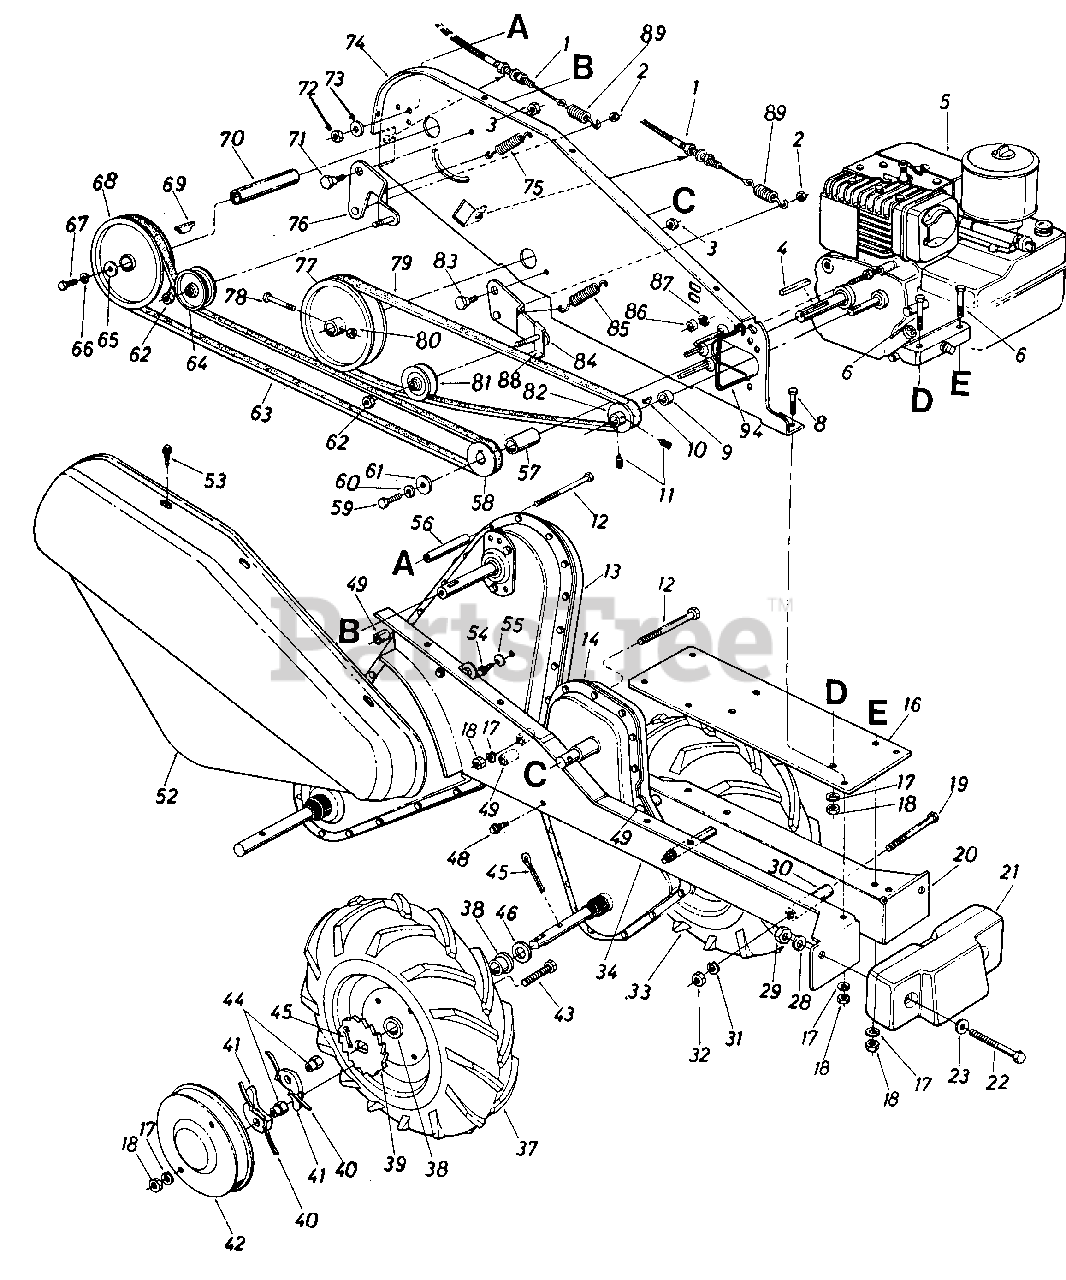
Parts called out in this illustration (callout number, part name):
1	CONTROL-CLUTCH
2	NUT-HEX CENTER L-1/4-20
3	NUT-HEX CENTER L-JAM
4	KEY-SQ 3/16 X .75
6	SCREW-HEX 5/16-18 X 1.50
8	SCREW-HEX 5/16-18 X .75
10	KEY-HI-PRO #5-1/8X5/8 DIA
11	SCREW-SET 1/4-28 X .25
12	SCREW-HEX 5/16-18 X 3.00
18	NUT-HEX 5/16-18
19	SCREW-HEX 3/8-24 X 3.0 LG
22	SCREW-HEX 1/2-13 X 4.0
23	WASHER-FL
28	WASHER-LOCK-1/2
29	NUT-HEX 1/2-13
31	WASHER-LOCK-3/8
32	NUT-HEX 3/8-24
33	WHEEL ASSY W/TIRE-LH
38	BEARING-FLANGE
40	SPRING-NYLON
41	PAWL
42	COVER-WHEEL
43	SCREW-HEX 5/16-24 X 1.25
44	NUT-HEX 5/16-18 SPEC
45	PIN-COTTER-1/8 DIA X 1.25
46	WASHER-FL-.885 ID X 1.37 OD X .060
48	SCREW-HEX WASH SF TAPP
52	COVER-BELT
53	SCREW-HEX WASH SF TAPP
54	SCREW-TAP 1/4-20 X .38
55	WASHER-SPRING BELL
59	SCREW-HEX SPECIAL 5/16-24X1.0
60	WASHER-LOCK-5/16
61	WASHER-5/16 X 1.25 X 1.27
62	NUT-HEX INS L-3/8-24
63	BELT-V 1/2 X 54
64	PULLEY-IDLER
65	WASHER-FL
66	WASHER-FL
67	SCREW-HEX 1/4-28 X .75
68	PULLEY
69	KEY-3/16 X 5/8
71	SCREW-SHLD
72	NUT-HEX 5/16-18
73	WASHER-LOCK-5/16
74	PLATE ASSY-SIDE
75	SPRING-EXTENSION
76	BRACKET ASSY-TINE
78	SCREW-HEX
79	BELT-V 1/2 X 43
80	NUT-HEX CENTER L-1/4-28
81	PULLEY-3 V IDLER
83	SCREW-SHLD .500 DIA X .170
84	BRACKET ASSY-WHL
85	SPRING-EXTENSION
86	NUT-HEX 1/4-20
87	WASHER-SPRING BELL
88	BRACKET-BELT GUARD
89	SPRING-EXTENSION
94	GUARD-BELT
